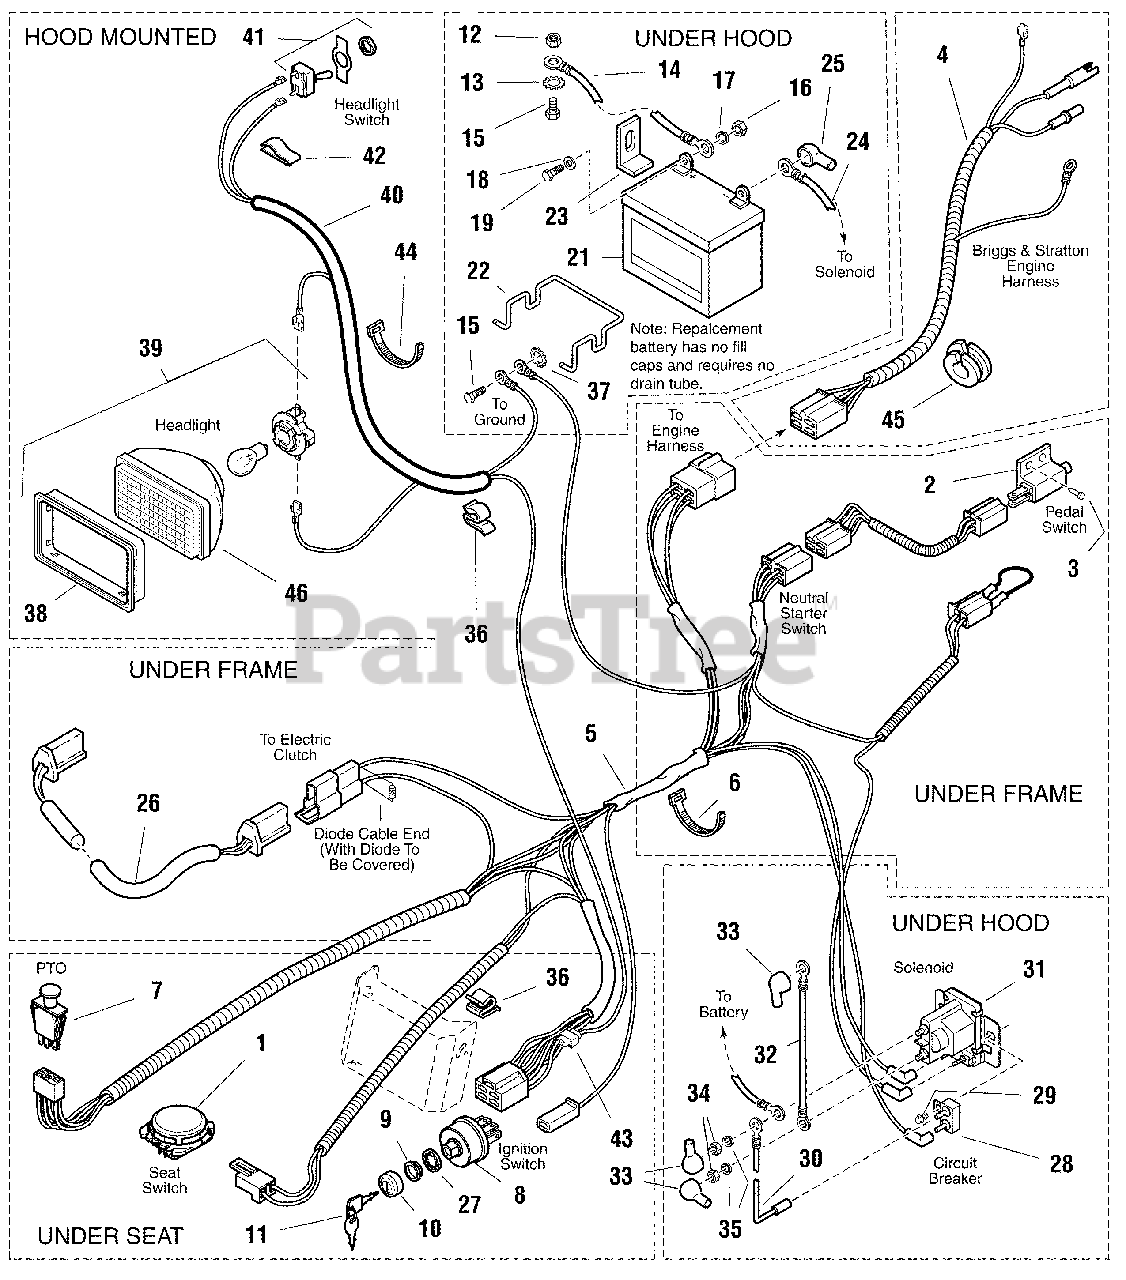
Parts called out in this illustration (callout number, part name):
1	SWITCH, Seat
2	SWITCH, Neutral Start
4	WIRE ASSEMBLY, Harness to Engine, Briggs & Stratton
5	HARNESS, Wiring
6	TIE, Self-Locking
7	SWITCH, PTO, Electric Clutch
8	SWITCH, Ignition (6 pole), (Includes Ref. Nos. 9, 10, 11 & 27)
9	NUT
10	COVER, Keyswitch
11	KEYS (Set of 2 Keys)
12	NUT, Metric, M08-1.25
13	WASHER, Lock, External Tooth, 3/8
14	CABLE, Battery
15	CAPSCREW, Metric, M08-1.25 x 20 mm
16	NUT, Hex, 1/4-20
17	WASHER, Lock, 1/4
18	WASHER
19	CAPSCREW, Hex Head, 1/4-20 x 3/4
22	BRACE, Battery
23	HOLDDOWN, Battery
24	CABLE, Battery to Solenoid, 37-3/4" Long
24	CABLE, Battery to Solenoid, 32-3/4" Long
25	BOOT, Insulator
26	WIRE ASSEMBLY, Clutch
27	WASHER, Internal Tooth, 5/8
28	CIRCUIT BREAKER
29	CAPSCREW, Hex Washer Head, Taptite, 1/4-20 x 1/2
30	WIRE ASSEMBLY, 12 Ga. 5-5/16 Long
31	SOLENOID
32	CABLE, Solenoid to Starter
33	COVER, Terminal
34	NUT, Hex, 5/16-24
35	WASHER, Lock, 5/16
37	WASHER, Lock, External Tooth, 5/16
39	HEADLIGHT ASSEMBLY
40	WIRING HARNESS, Light
41	SWITCH, Toggle
42	CLIP, Tinnerman
43	SPLICE, Connector
44	TIE, Self Locking
46	HEADLIGHT HOUSING
